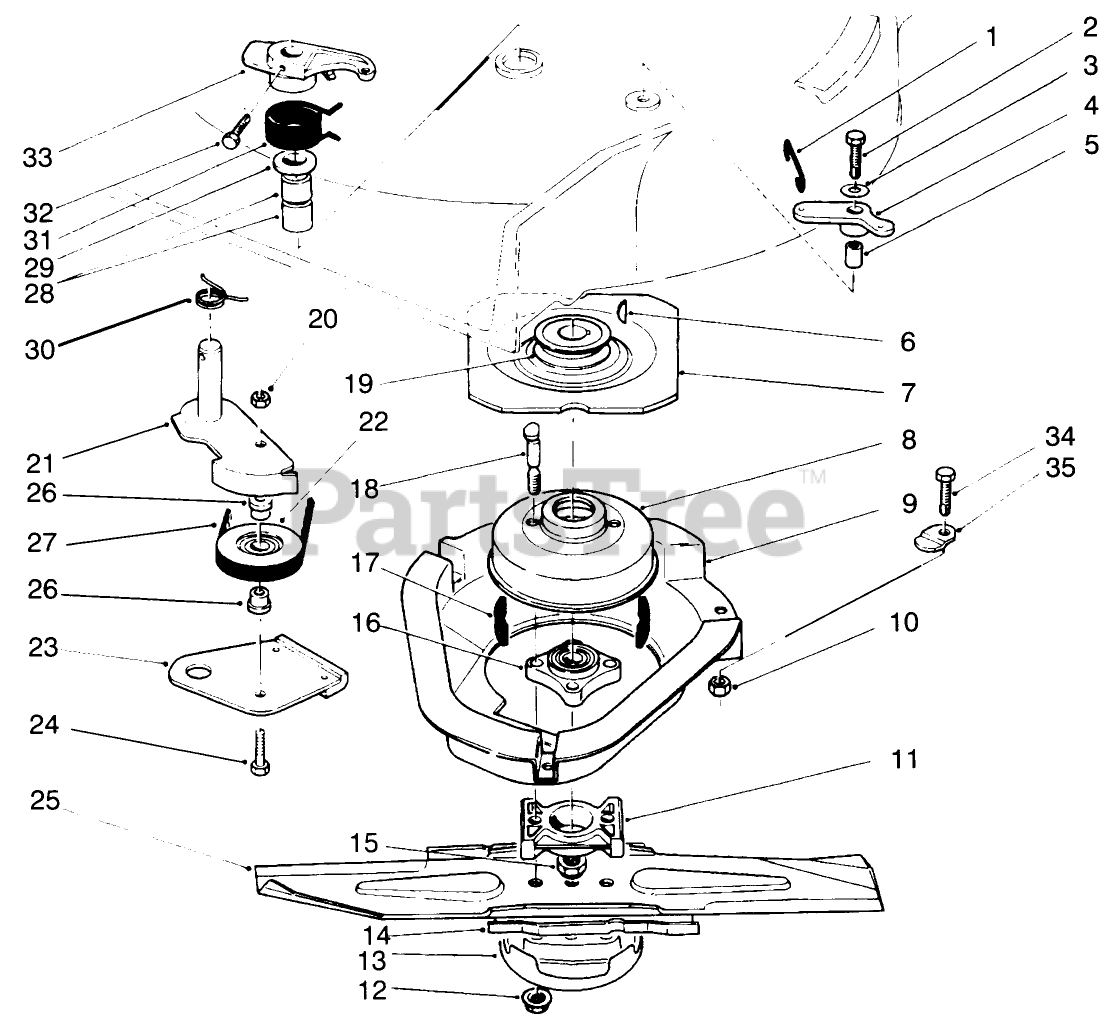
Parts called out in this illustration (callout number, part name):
1	LINK-CONTROL
3	WASHER-PLAIN
4	BELLCRANK
5	SLEEVE-BELLCRANK
6	KEY-WOODRUFF
10	NUT-LOCK, NI
12	NUT-LOCK
13	CUP-SCALP, ANTI
15	NUT-LOCK, NI
16	HUB ASM
17	DAMPENER-VIBRATION
18	BOLT-BLADE
19	PULLEY-DRIVER
20	NUT-LOCK, NI
21	ARM-IDLER
24	SCREW-HH
26	SPACER-PULLEY, IDLER
27	V-BELT
28	BEARING
29	WASHER
30	SPRING-TORSION
31	SPRING-TORSION
32	SCREW-HH
33	LEVER
34	SCREW-HH
35	SHIELD-RETAINER
